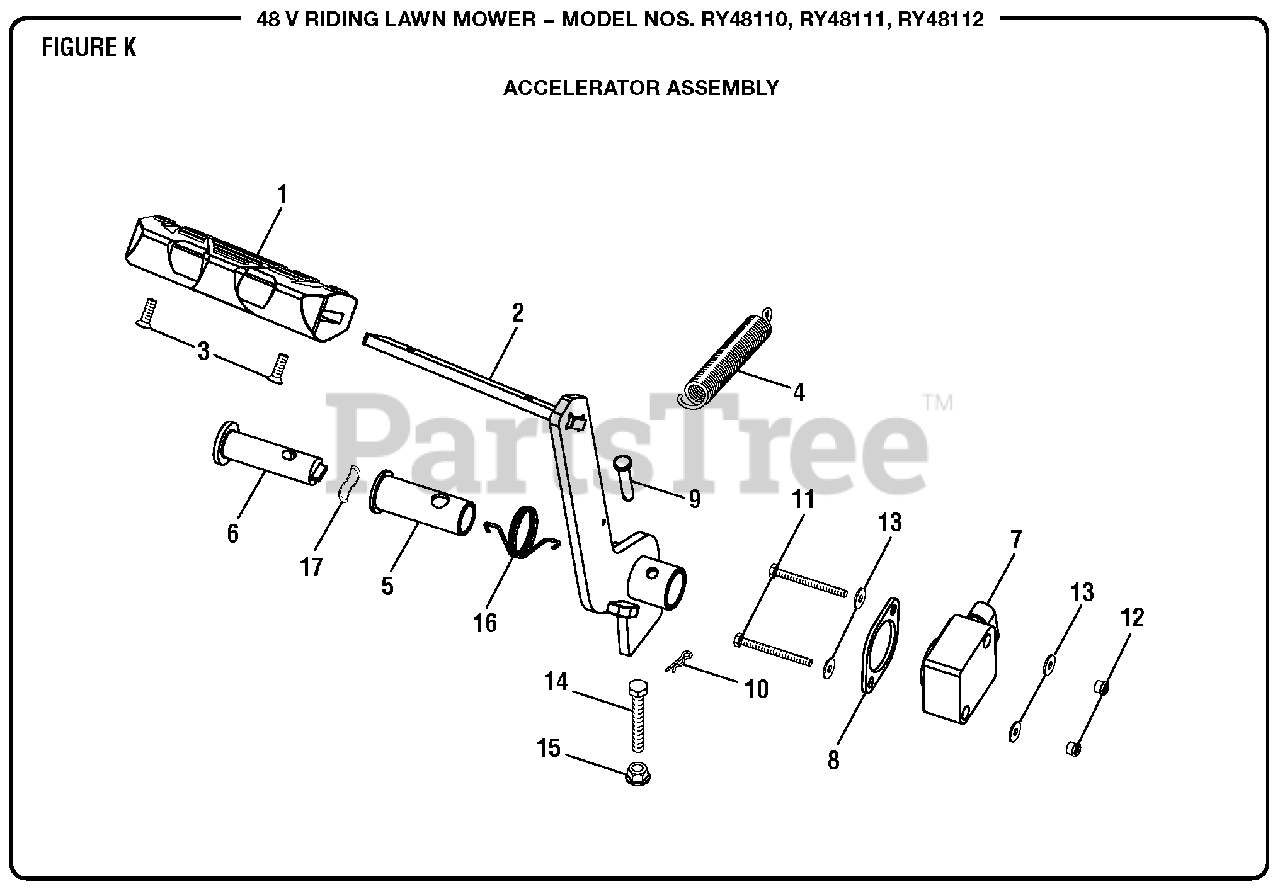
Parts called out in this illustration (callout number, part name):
1	Brake Pedal
2	Acceleration Pedal
3	Screw (M5 x 16 mm, Flat Hd.)
4	Pedal Spring
5	Accelerator Axle Bushing
6	Accelerator Axle
7	Speed Control Switch
8	Control Switch Mounting Bracket
9	Clevis Pin (6 x 30 mm)
10	Cotter Pin (6 mm)
11	Bolt (M4 x 45 mm, Hex Hd.)
12	Nut (M4 x 0.7, Lock)
13	Washer (OD12 x ID4.3 x 1t)
14	Bolt (M6 x 45 mm, Hex Hd.)
15	Flange Nut (M6)
16	Torsion Spring
17	Wavy Washer
